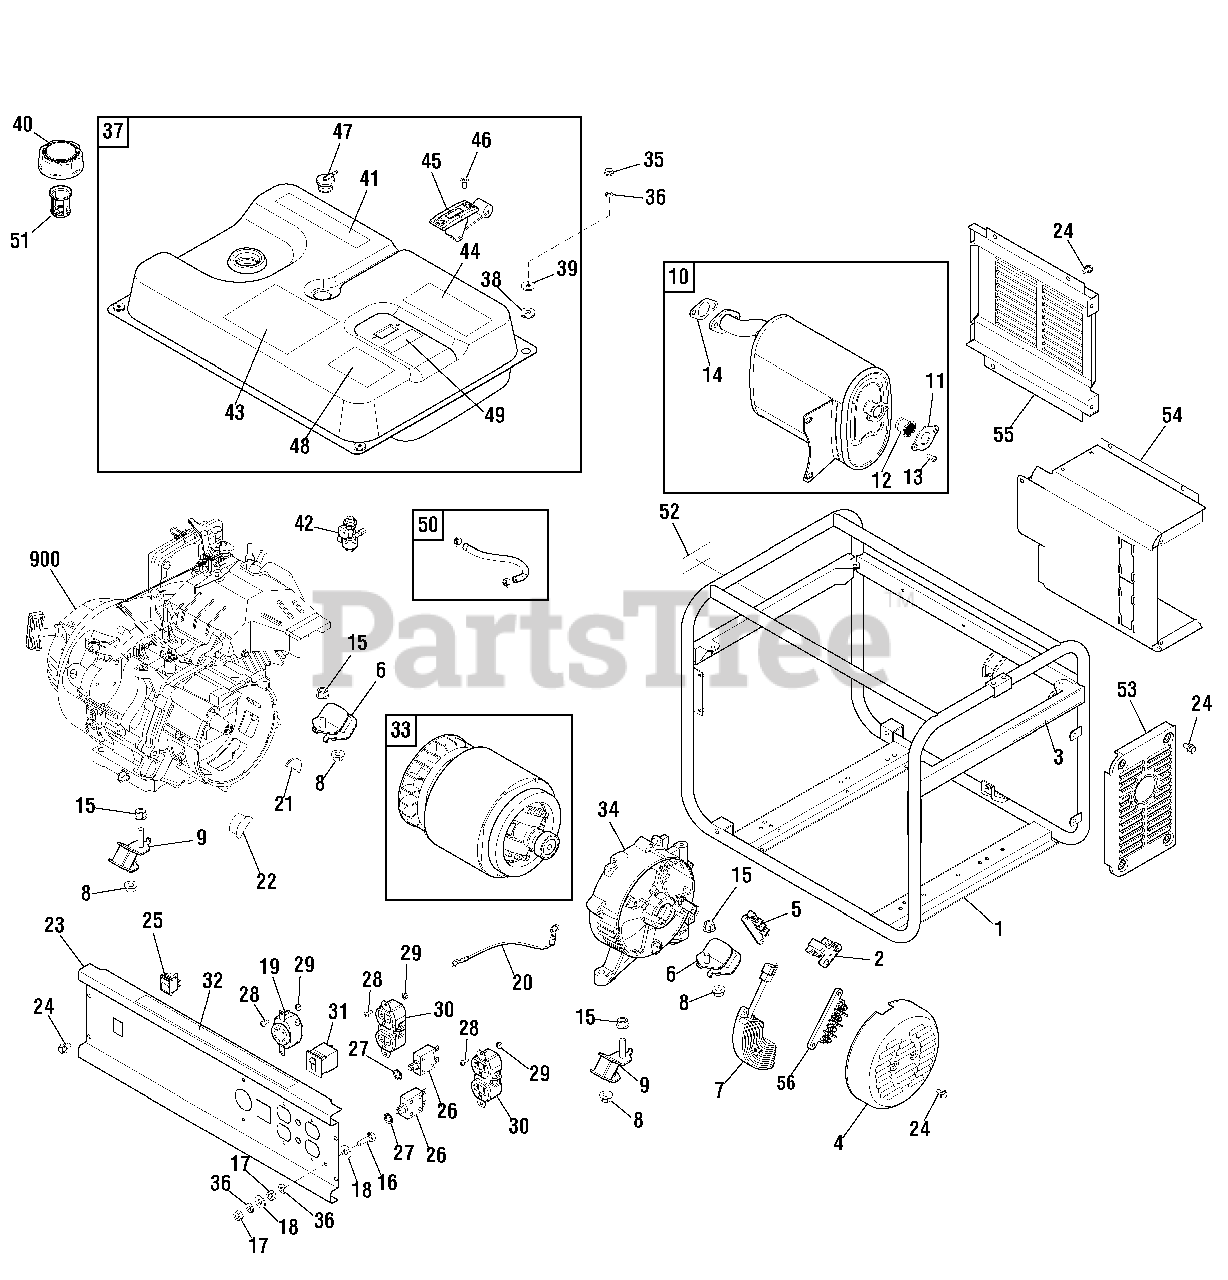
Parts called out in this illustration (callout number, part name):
6	MOUNT-VIBRATION
7	VOLTAGE REGULATOR
8	* NUT, Flange, M8
9	MOUNT-VIBRATION
12	SPARK ARRESTOR
13	* SCREW, M5 x 12
14	GASKET-MUFFLER
15	* NUT, Flange, M10
16	* BOLT, M6 x 22
17	* NUT, M6
18	* WASHER, Flat, M6
23	PANEL-CONTROL
24	* BOLT, M6 x 12
26	BREAKER-CIRCUIT
28	* SCREW, M4 x 14
29	* NUT, Flange, M4
31	BREAKER-CIRCUIT
34	CARRIER-BEARING
35	* BOLT, M6 x 20
36	* WASHER, Lock, M6
38	MOUNT-VIBRATION
46	* SCREW, M5 x 10
50	KIT-FUEL HOSE
56	TERMINAL BLOCK
900	** ENGINE
